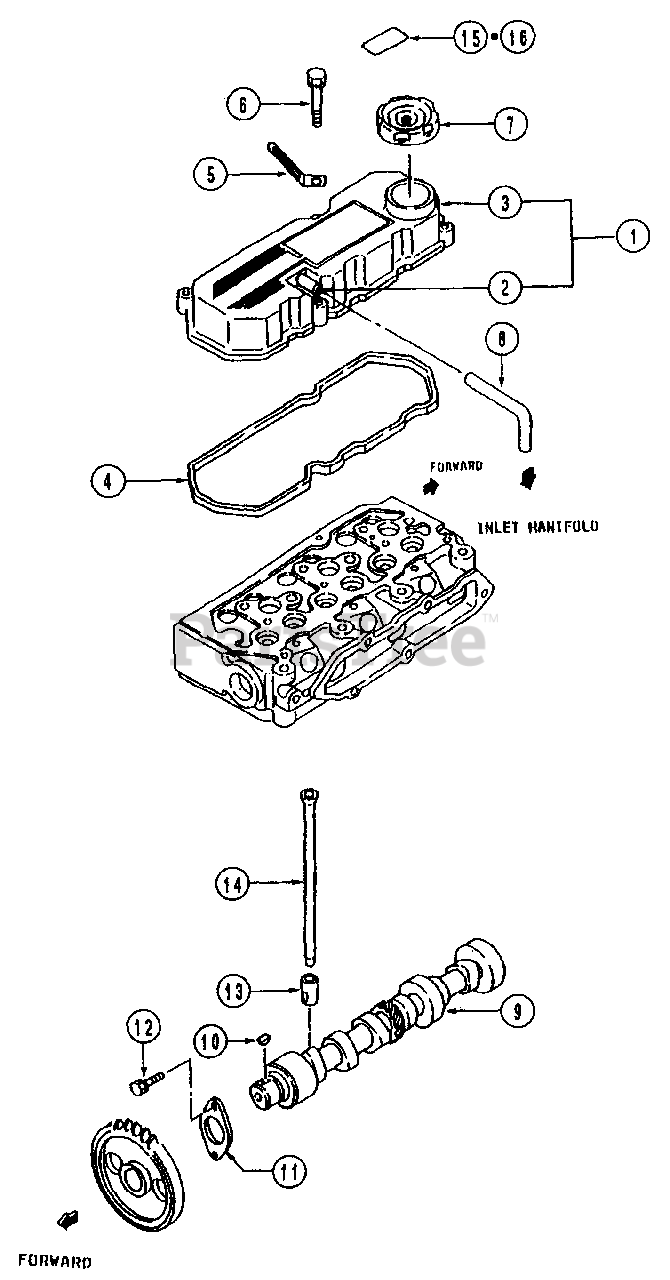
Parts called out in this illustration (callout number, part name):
1	Cover Ass'y., Rocker
2	Pipe
3	Cover, Rocker
4	Gasket, Rocker
6	Bolt, W/Washer
8	Breather, Pipe
9	Camshaft
10	Key, Woodruff
11	Plate, Thrust
12	Bolt, W/Washer
13	Tappet
15	Label, Model (Gear)
16	Label, Model (HST)
